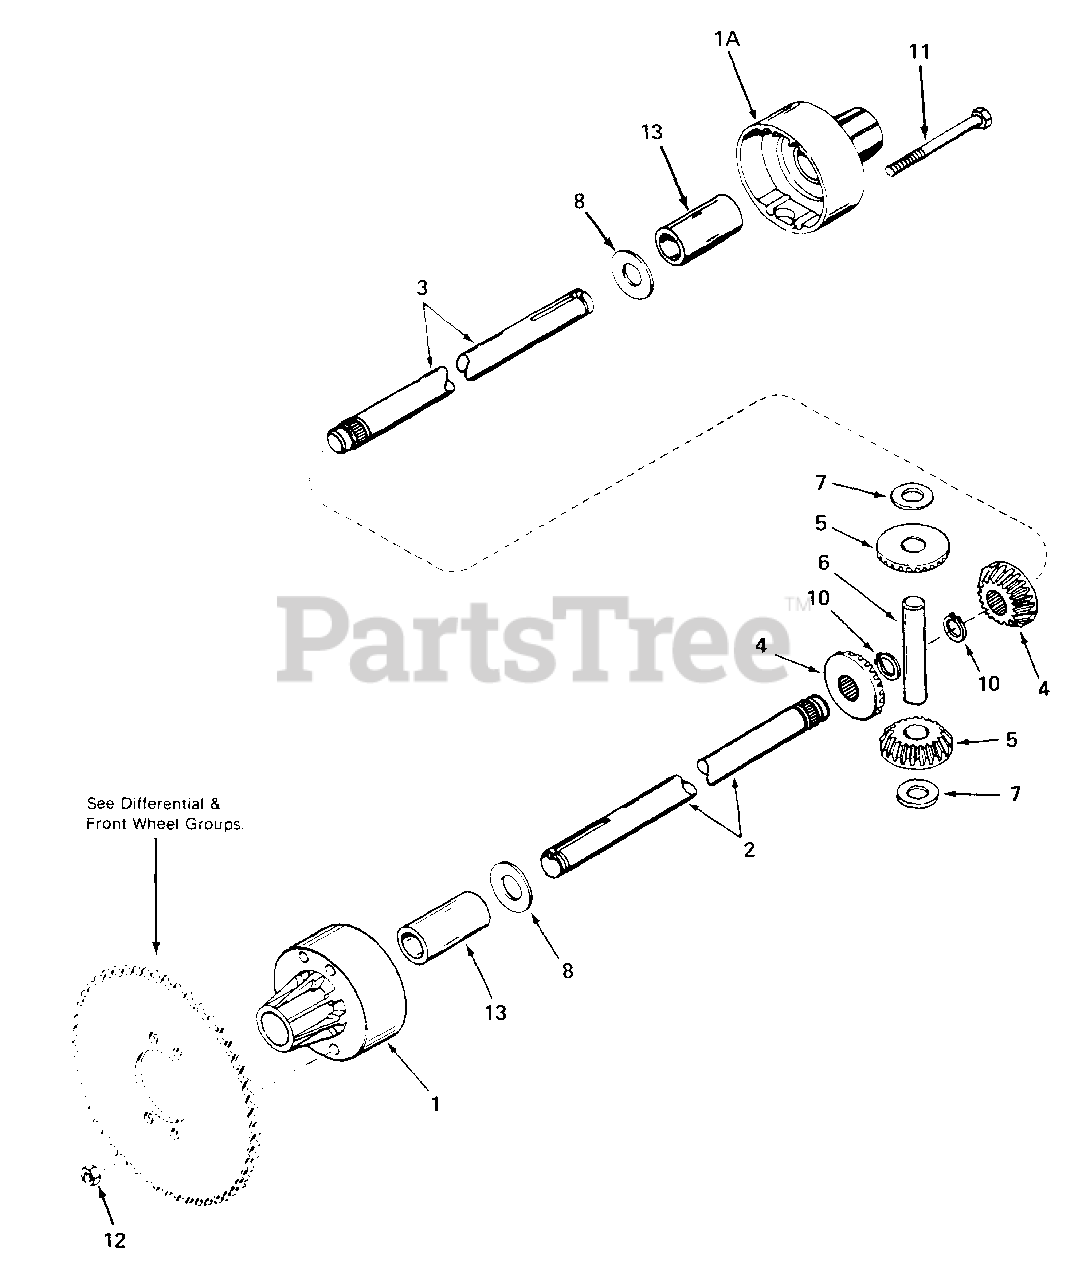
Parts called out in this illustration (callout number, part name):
1	HOUSING, Differential Carrier (Incl. Ref. No. 13)
1A	HOUSING, Differential Carrier (Incl. Ref. No. 13)
2	AXLE (8/78" Long)
3	AXLE (22-1/4" Long)
4	GEAR, Bevel
5	GEAR, Pinion
6	PIN, Drive
7	WASHER, Thrust
10	RING, Snap
11	SCREW, Flanged Hex Hd., 5/16-18 x 3-15/16
12	NUT, Lock, 5/16-18
